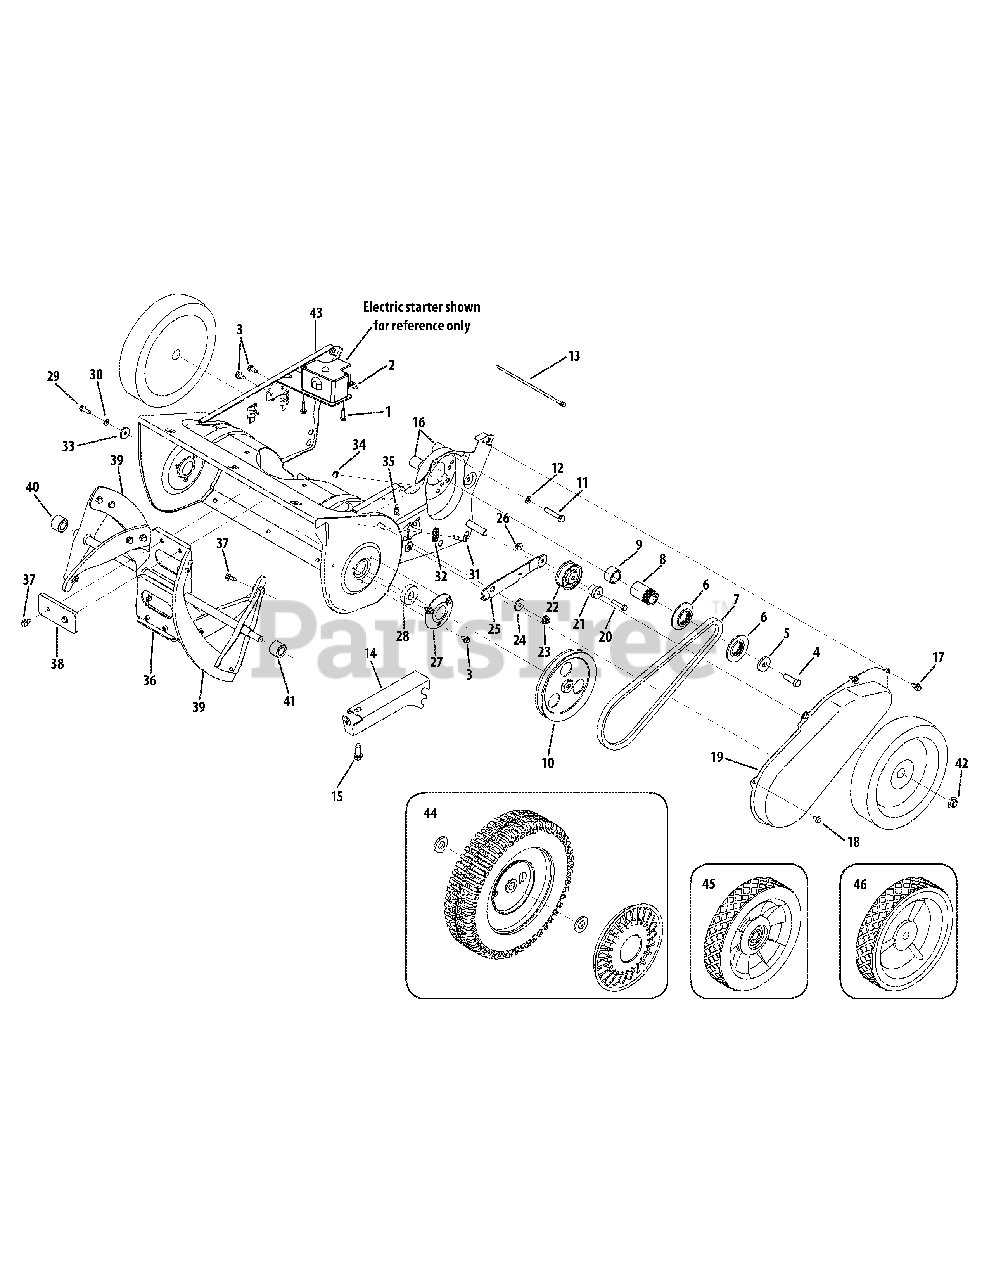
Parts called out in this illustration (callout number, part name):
1	Hex Screw, #12-16 x .75
2	Electric Starter Support Bracket
3	Hex Screw, 1/4-14 x .500
4	Hex Screw, 3/8-24 x 1.25
5	Flat Washer, .406 x 1.25 x .157
6	Pulley Half, 4L-V x 2.30 OD
7	V-Belt
8	Spacer, .875 ID x 1.185 OD
9	Spacer, .88 ID x 1.18 OD x .74 Lg.
10	V-Type Pulley, 1/2 x 35.7
11	Hex Screw, 5/16-24 x 1.75
12	Lock Washer, 5/16
13	Cable Tie, 7.5
14	Engine Support Bracket
15	Hex Washer Screw, 3/8-16 x 1.000
16	Spacer, .875 x .320 x 1.027
17	Hex Washer Screw, 1/4-14 x .625
18	Hex Washer Screw, 1/4-20 x .375
19	Belt Cover - MTD Red
19	Belt Cover - Oyster Gray
20	Hex Screw, 1/4-20 x 1.25
21	Shoulder Spacer, .260 x .785 x .538
22	Pulley Assembly, 1.917 OD
23	Flange Lock Nut, 5/16-18
24	Shoulder Spacer
25	Idler Bracket w/ Brake
26	Flange Lock Nut, 1/4-20
27	Bearing Cup
28	Ball Bearing, 1.25 x 37 x 12.6301
29	Hex Screw, 1/4-20 x .750
30	Lock Washer, 1/4
31	Shoulder Screw, .340 x .335 x 1/4-28
32	Cable Roller
33	Flat Washer, .265 x .938 x .120
34	Hex Lock Nut, 1/4-28
35	Extension Spring, .33 OD x 1.12
36	Auger Assembly, 21"
37	Hex Screw, 1/4-14 x .625
38	Rubber Pad
39	Spiral Crescent
40	RH Spacer
41	LH Spacer
42	Push Cap, 1/2
43	Auger Housing - MTD Red
43	Auger Housing - Oyster Gray
44	Wheel, 9 x 2.125
44	Hub Cap
44	Flat Washer, .510 x 1.000 x .125
45	Wheel, 7 x 1.5
46	Wheel, 7 x 1.61
